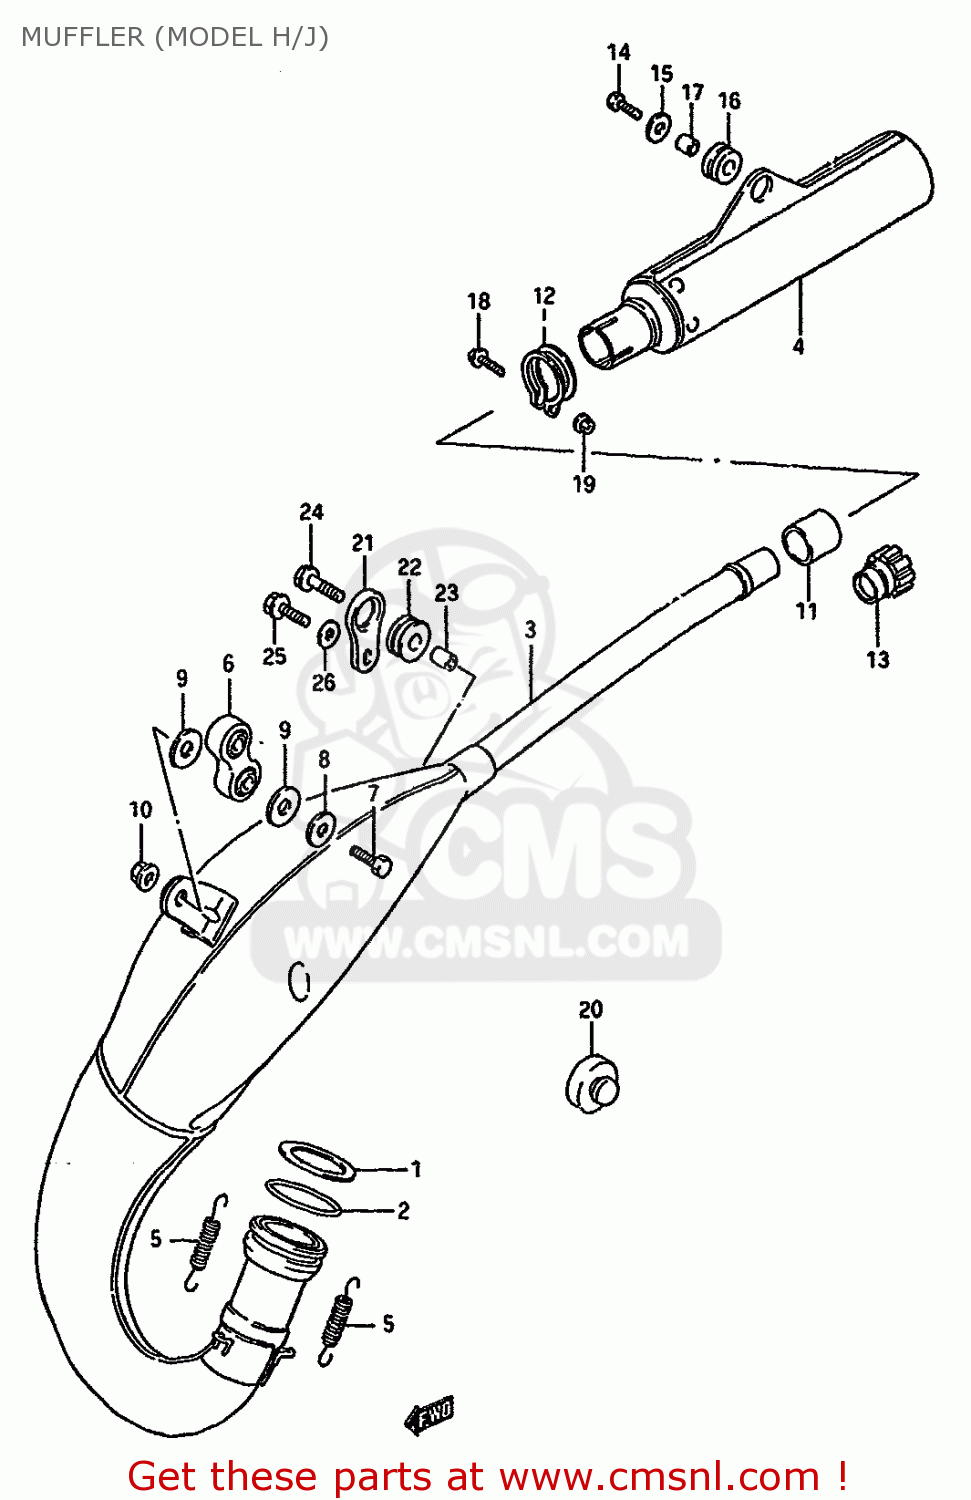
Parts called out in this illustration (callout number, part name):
1	GASKET,EXHAUST PIPE (NAS)
2	O-RING,EXHAUST
3	MUFFLER,1ST
4	MUFFLER,2ND
5	SPRING
6	DAMPER,MUFFLER
7	BOLT(8X32)
8	WASHER
9	WASHER(13X28X1.6)
10	NUT
11	GASKET,SECOND MUFFLER (NAS)
12	CLAMP,SECOND MUFFLER
13	CONNECTOR,MUFFLER
14	BOLT
15	WASHER (6.5X24X1.6)
16	CUSHION
17	SPACER (6.4X9X10.5)
18	BOLT 6X35
19	NUT 6MM
20	CUSHION
21	PLATE,MUFFLER MTG
22	CUSHION,MUFFLER
23	SPACER (6.4X9X13.5)
24	BOLT
25	BOLT
26	WASHER
